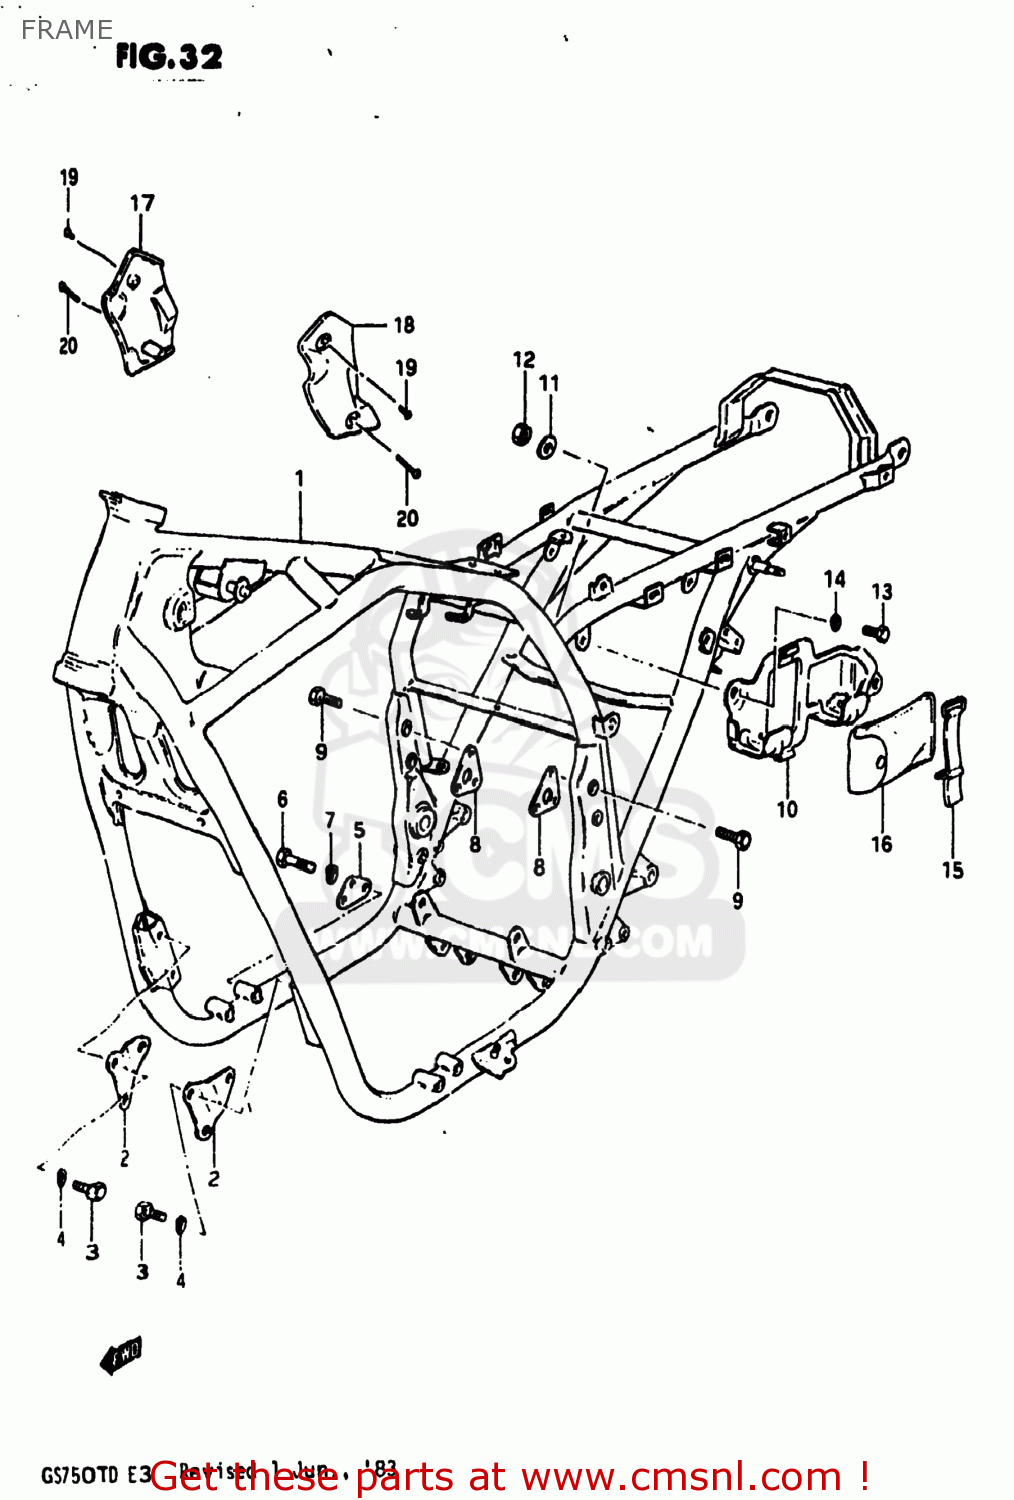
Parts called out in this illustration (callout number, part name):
1	FRAME
2	PLATE,ENGINE MOUNTING
3	BOLT
4	LOCK WASHER
5	PLATE,ENGINE MOUNTING
6	BOLT
7	LOCK WASHER
8	PLATE,ENGINE MOUNTING
9	BOLT
10	HOLDER,TOOL
11	WASHER(6.5X30X1.6)
12	NUT
13	BOLT
14	LOCK WASHER
15	BAND
16	TOOL ASSY
17	COVER,FRAME HEAD,RIGHT
18	COVER,FRAME HEAD,LEFT
19	SCREW 5X20
20	SCREW
